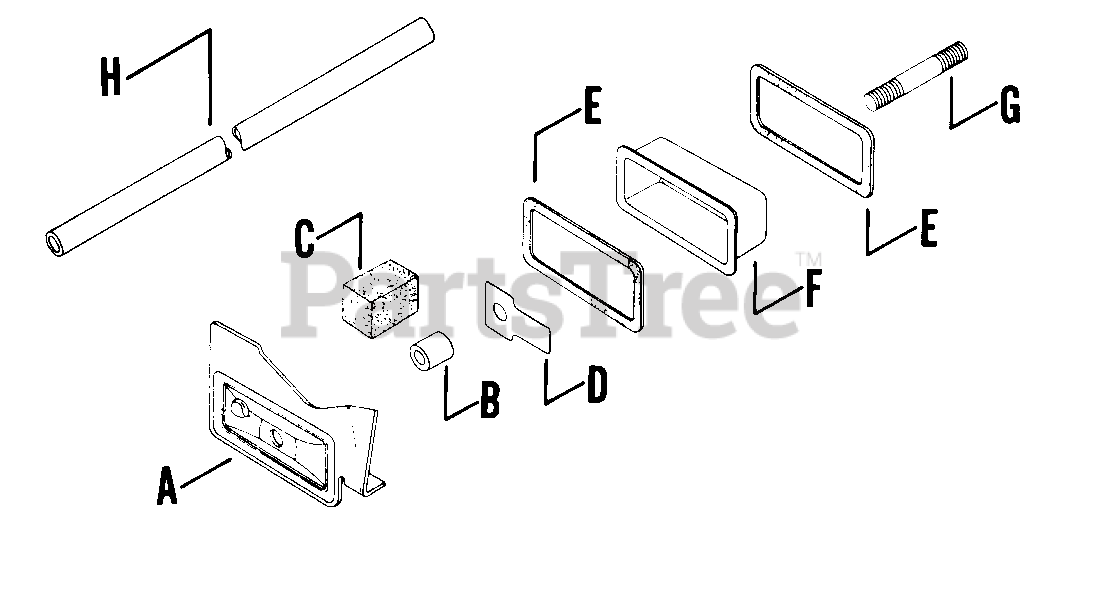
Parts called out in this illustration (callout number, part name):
A	COVER, VALVE - DISCONTINUED
C	FILTER - USE 231419
D	REED, BREATHER
F	PLATE - DISCONTINUED
G	STUD, 1/4-20x2-9/16" - DISC.
